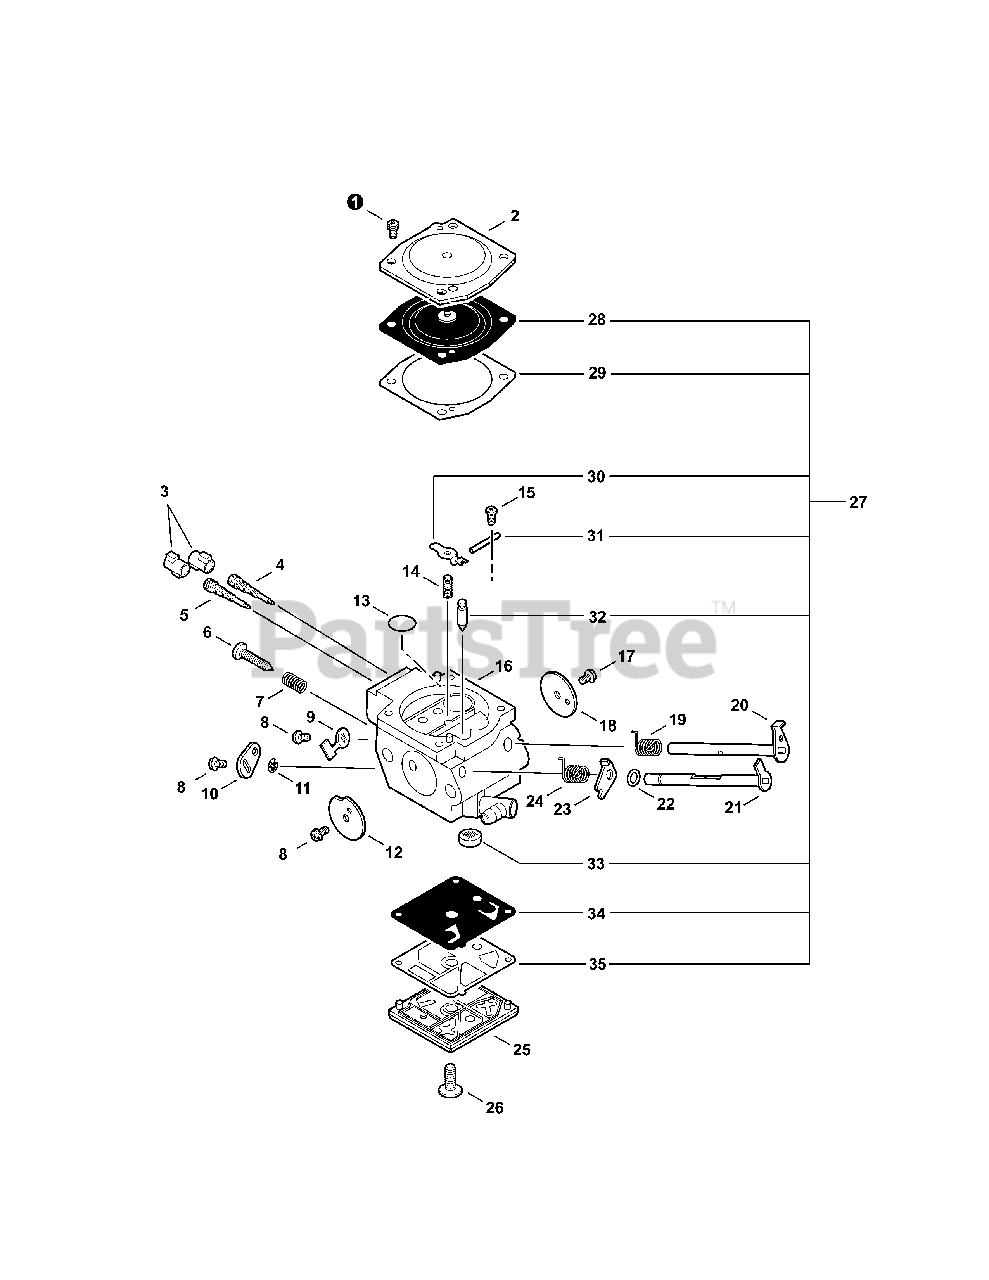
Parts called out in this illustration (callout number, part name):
2	COVER, DIAPHRAGM
3	CAP, LIMITER
4	NEEDLE - LOW SPEED
5	NEEDLE - HIGH SPEED
6	SCREW, IDLE ADJUST
7	SPRING, IDLE ADJUST
9	STOP, THROTTLE
10	LEVER, CHOKE
11	RING, RETAINING
12	VALVE, CHOKE
13	PLUG, WELCH
14	SPRING, METERING LEVER
15	SCREW, METERING LEVER PIN
16	BODY, CARBURETOR
17	SCREW, THROTTLE VALVE
18	VALVE, THROTTLE
19	SPRING, THROTTLE RETURN
20	SHAFT, THROTTLE
21	SHAFT, CHOKE
23	LEVER, FAST IDLE
24	SPRING, CHOKE RETURN
25	COVER, PUMP
27	REPAIR KIT
28	DIAPHRAGM, METERING
29	GASKET, METERING
30	LEVER, METERING
31	PIN, METERING LEVER
32	VALVE, INLET NEEDLE
33	STRAINER
34	DIAPHRAGM, PUMP
35	GASKET, PUMP
